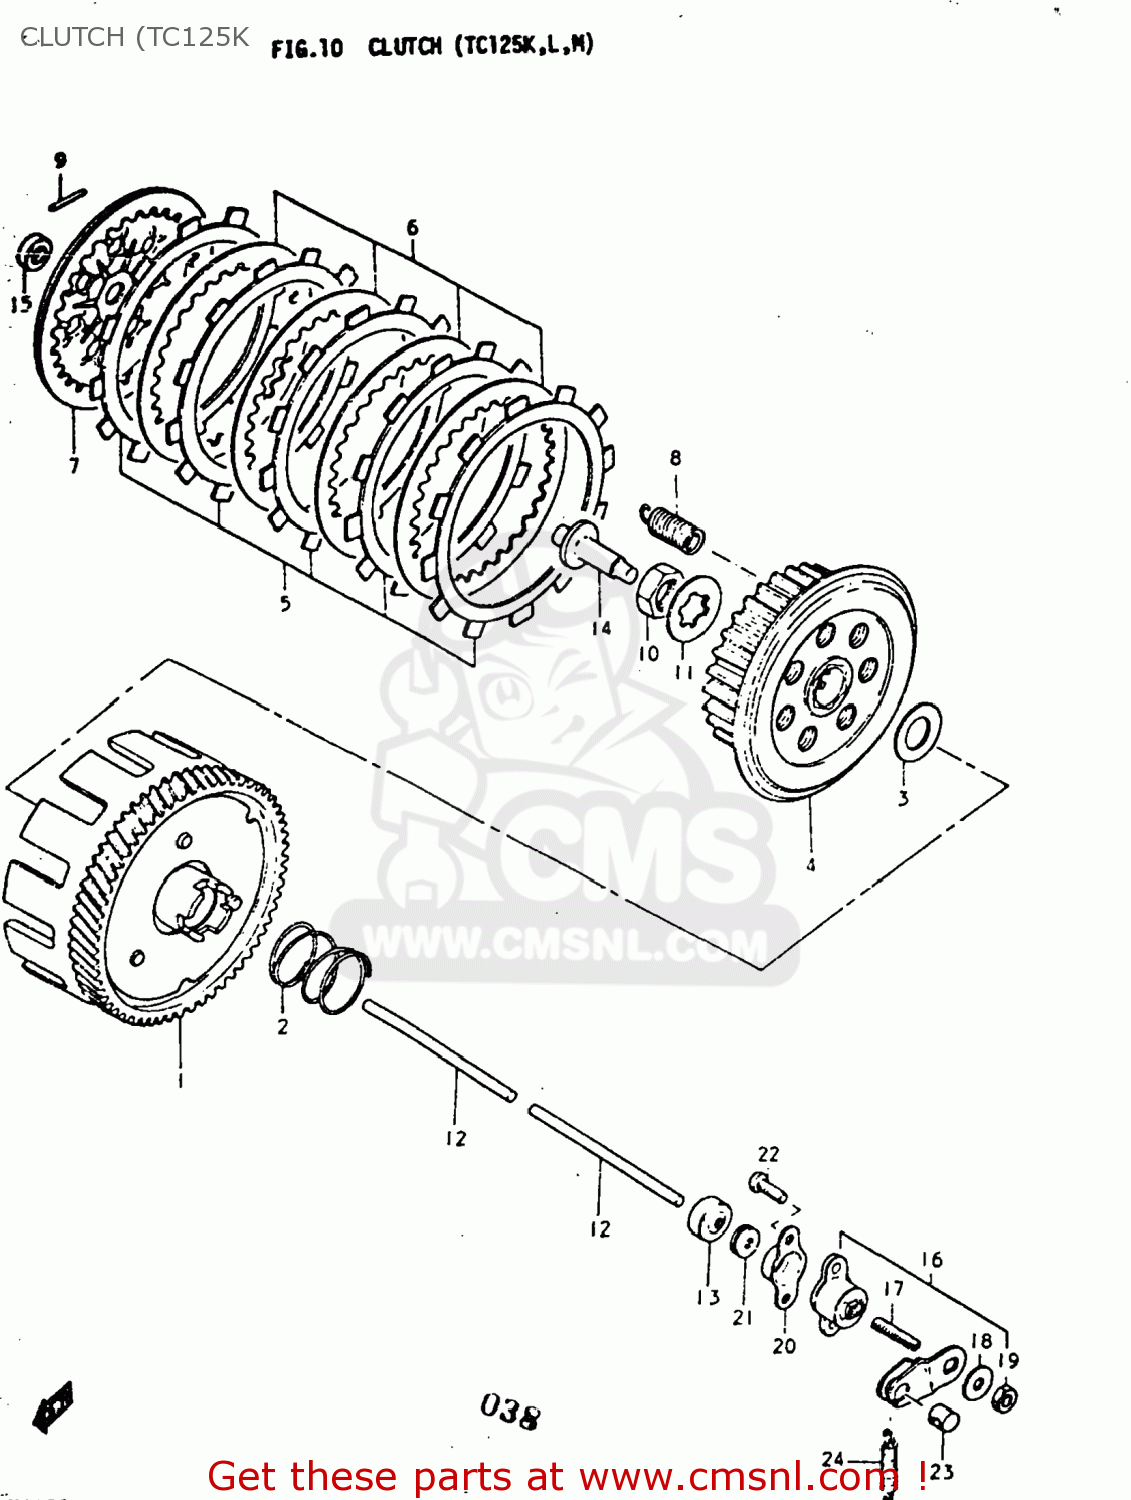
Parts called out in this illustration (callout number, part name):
1	GEAR ASSEMBLY,PRIMARY DRIVE
2	SPRING
3	WASHER
4	HUB,CLUTCH SLEEVE
5	PLATE,CLUTCH DRIVE
6	PLATE,CLUTCH DRIVEN (NAS)
7	PLATE,CLUTCH PRESSURE
8	SPRING
9	PIN(2.5X19.8)
10	NUT
11	WASHER,LOCK
12	ROD,CLUTCH PUSH
13	OIL SEAL
14	ROD,CLUTCH RELEASE
15	SEAL,OIL (10X17X5)
16	SCREW ASSY,CLUTCH RELEASE
17	SCREW
18	WASHER(6.5X16X1.2)
19	NUT
20	COVER,CLUTCH RELEASE SCREW
21	SEAL,DUST(5.3X13X5)
22	SCREW
23	PIECE,RELEASE ARM END
24	SPRING
